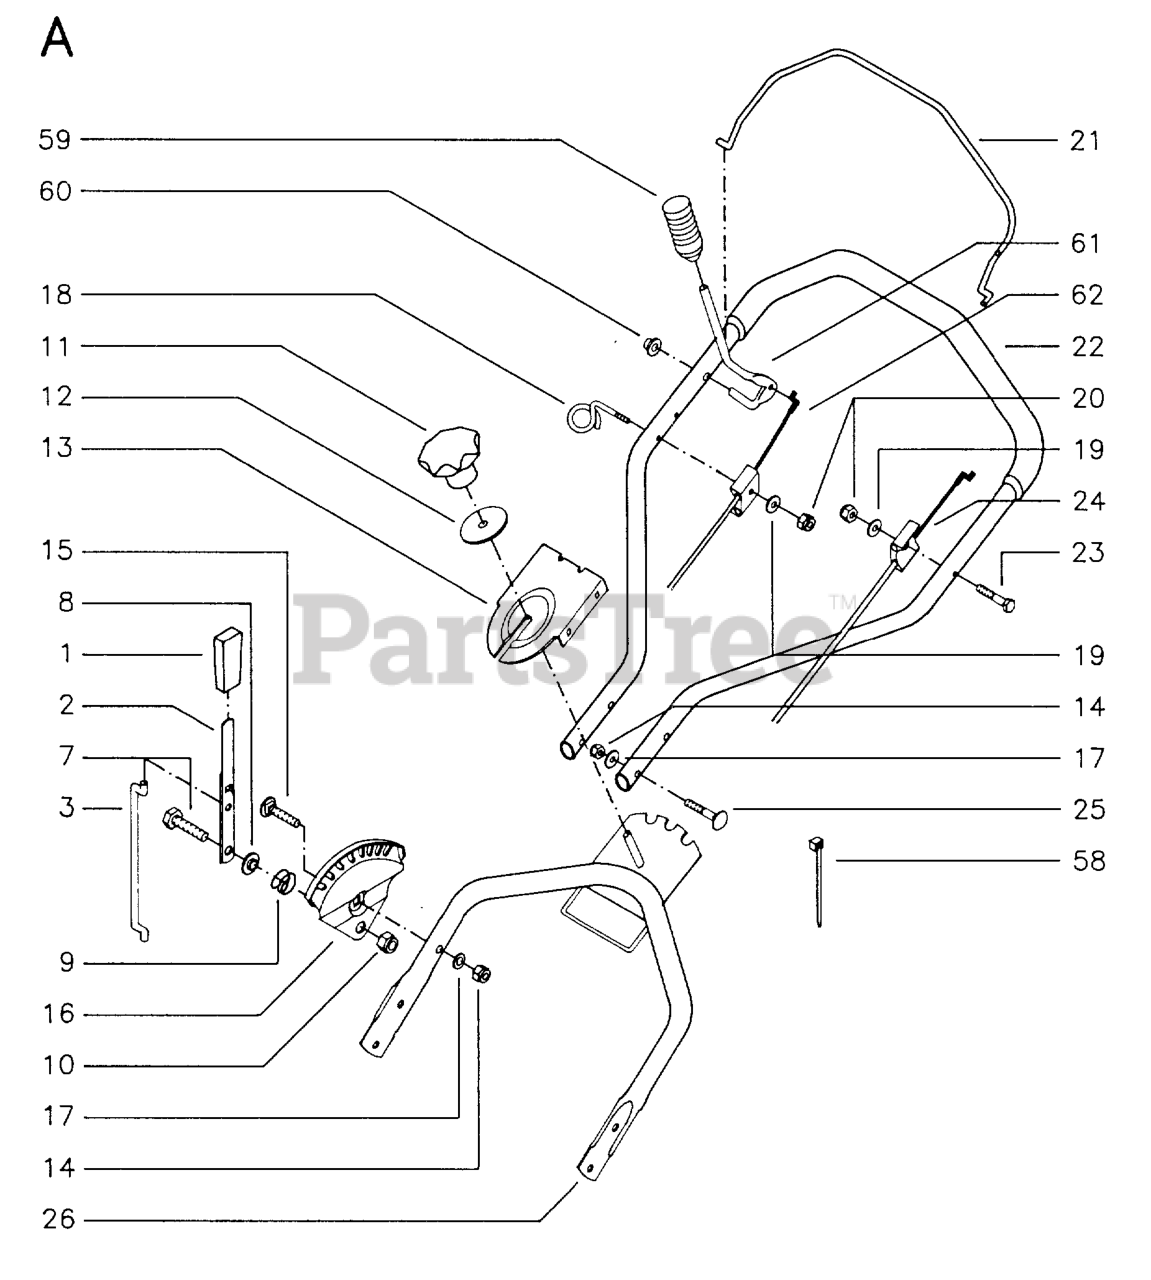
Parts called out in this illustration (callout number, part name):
2	CLUTCH ARM
9	PRESSURE SPRING
14	LOCKNUT M8
17	WASHER - 15X7.3X1.6
20	LOCKNUT M6
23	BOLT FLANGE
